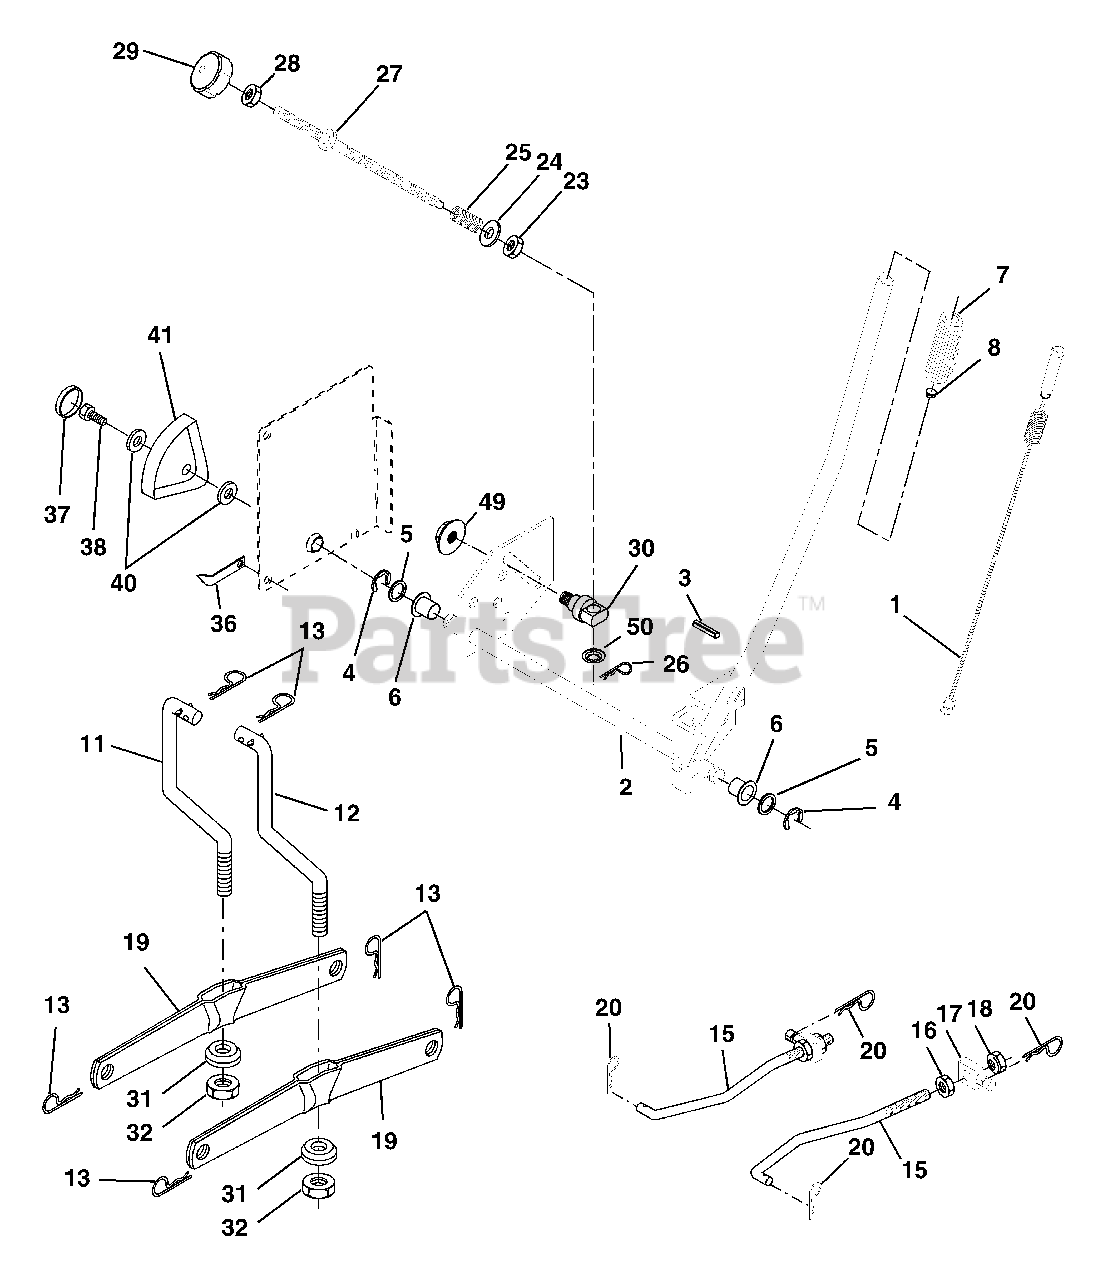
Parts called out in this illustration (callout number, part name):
1	Washer Asm Inner Spring W/Plunger
2	Shaft Asm. Lift
3	Pin Groove
4	E Ring #5133-62
5	Washer 21/32 x 1 x 21 Ga.
6	Bearing Nylon
7	Grip Handle
8	Button Plunger Black
11	Link Asm Lift L.H.
12	Link Asm Lift R.H.
13	Retainer Spring
15	Link Front
16	Nut Jam Hex 1/2-13 Unc
17	Trunnion Blk Zinc
18	Nut Lock W/Wsh 1/2-13 Unc
19	Arm Suspension Mower
20	Retainer Spring
23	Nut Special
24	Washer 13/32 x 5/8 x 16 Ga.
25	Spring 2-1/8
26	Retainer Clip
27	Rod Adj Lift Zinc
28	Nut Hex Jam 3/8-16 Unc
29	Knob Inf 3/8-16 unc
30	Trunnion Infin Height
31	Bearing, Pvt. Lift. Spherical
32	Nut Crownlock 3/8-24
36	Pointer Height Indicator
37	Plug Hole Blk
38	Screw 5/16-18 x 1
40	Washer 11/32 x 1-1/2 x 10 Ga
41	Scale Ind Height Blk
49	Nut Hex flange lock
50	Nut Push Phos & Oil
51	Retainer Spring
